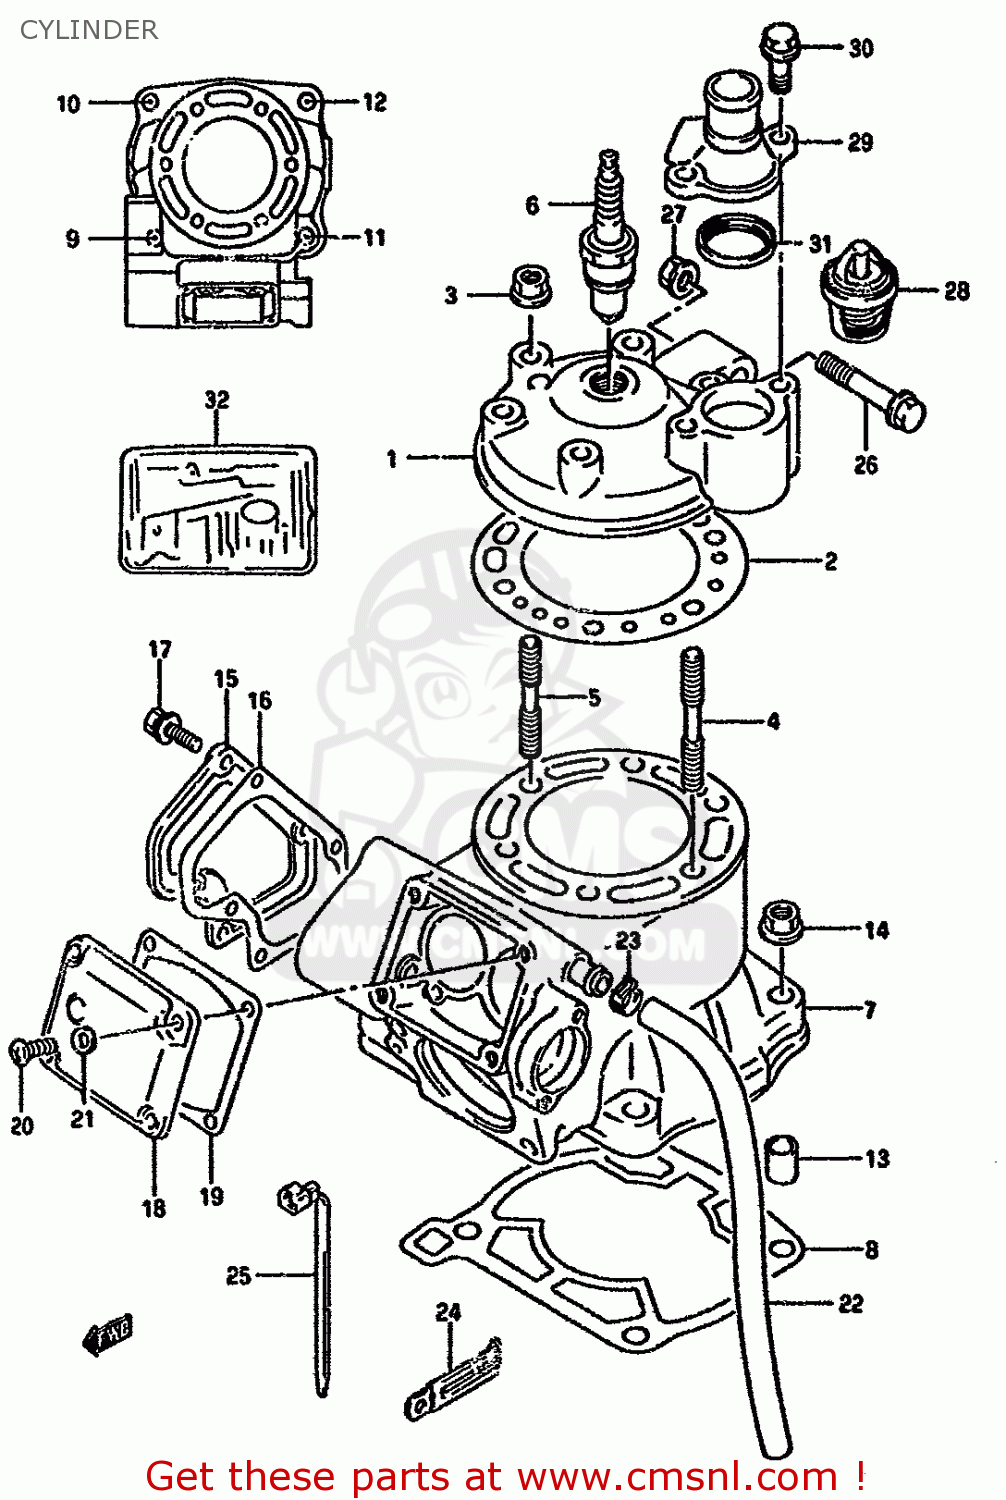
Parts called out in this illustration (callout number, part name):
1	HEAD,CYLINDER
2	GASKET,CYLINDER HEAD
3	NUT
4	STUD BOLT (L:76)
5	BOLT,STUD
6	SPARK PLUG BR9EV
7	CYLINDER SET
8	GASKET,CYLINDER (NAS)
9	STUD 10X30
10	STUD BOLT
11	STUD BOLT (L:40)
12	STUD BOLT (L:45)
13	PIN
14	NUT
15	COVER,CYLINDER NO.1
16	GASKET,CYL COVER NO.1 (NAS)
17	BOLT
18	COVER,CYLINDER NO.2
19	GASKET,CYLINDER COVER (NAS)
20	SCREW
21	GASKET(5.3X9.3X1.2) (NAS)
22	HOSE
23	CLIP
24	CLAMP
25	CLAMP(L:125)
26	BOLT(8X45)
27	NUT
28	THERMOSTAT,WATER 60 DEG
29	COVER,THERMOSTAT
30	BOLT
31	SEAL,THERMOSTAT COVER
32	GASKET SET (NAS)
